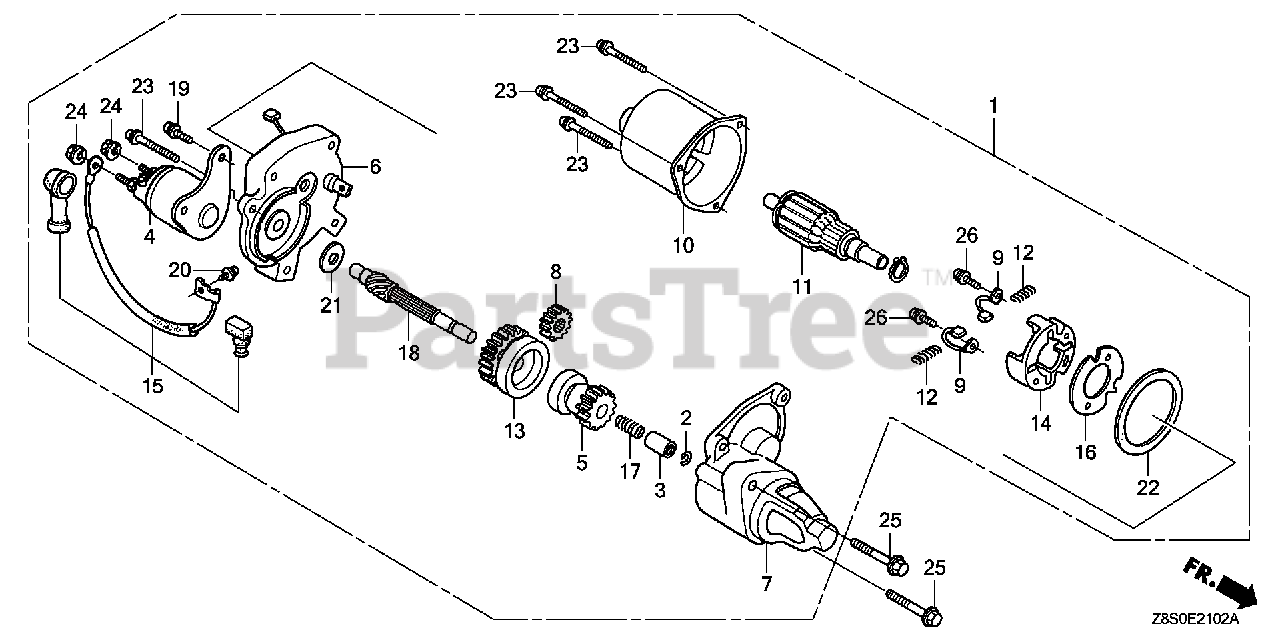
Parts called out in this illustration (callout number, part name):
1	STARTER MOTOR ASSY.
2	RING, SNAP
3	COLLAR, CLUTCH
4	CONTACTOR ASSY.
5	CLUTCH, OVERRUNNING
6	BRACKET, CENTER
7	BRACKET, FR.
8	GEAR, DRIVE PINION
9	BRUSH
10	YOKE
11	ARMATURE
12	SPRING, BRUSH RETURN
13	GEAR, REDUCTION
14	HOLDER, BRUSH
15	WIRE, WATER COVER
16	INSULATOR
19	BOLT-WASHER (5X14)
20	SCREW-WASHER (4X6)
21	WASHER, SK
22	GASKET
23	SCREW-WASHER (5X3)
24	NUT-WASHER (6MM)
25	BOLT, FLANGE (8X40) Use up to Engine SN 1003236.
26	SCREW-WASHER (4X14)
